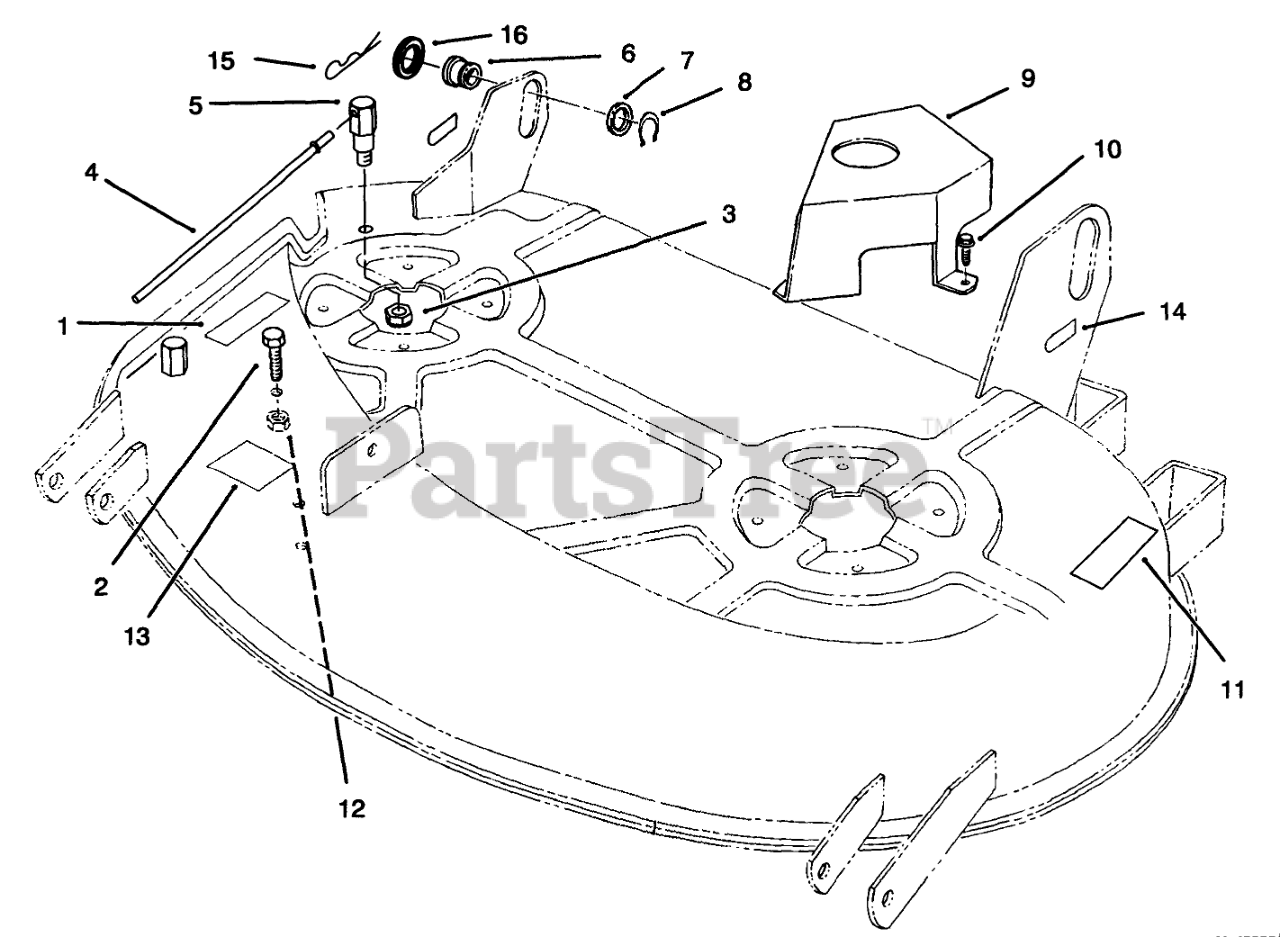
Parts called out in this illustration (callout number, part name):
1	DECAL-CAUTION
2	SCREW-HH
3	NUT-LOCK, NI
4	ROD-HINGE DEFLECTOR
5	PIVOT POST - REAR
6	ROLLER-LIFT
7	Washer
8	RING-RETAINING
9	COVER-BELT
10	SCREW-HWHTF
11	DECAL-DANGER
12	NUT-LOCK, NI
13	Decal-Routing
14	DECAL-ATTACH-A-MATIC
15	Pin-Cotter
16	WASHER-FLAT
